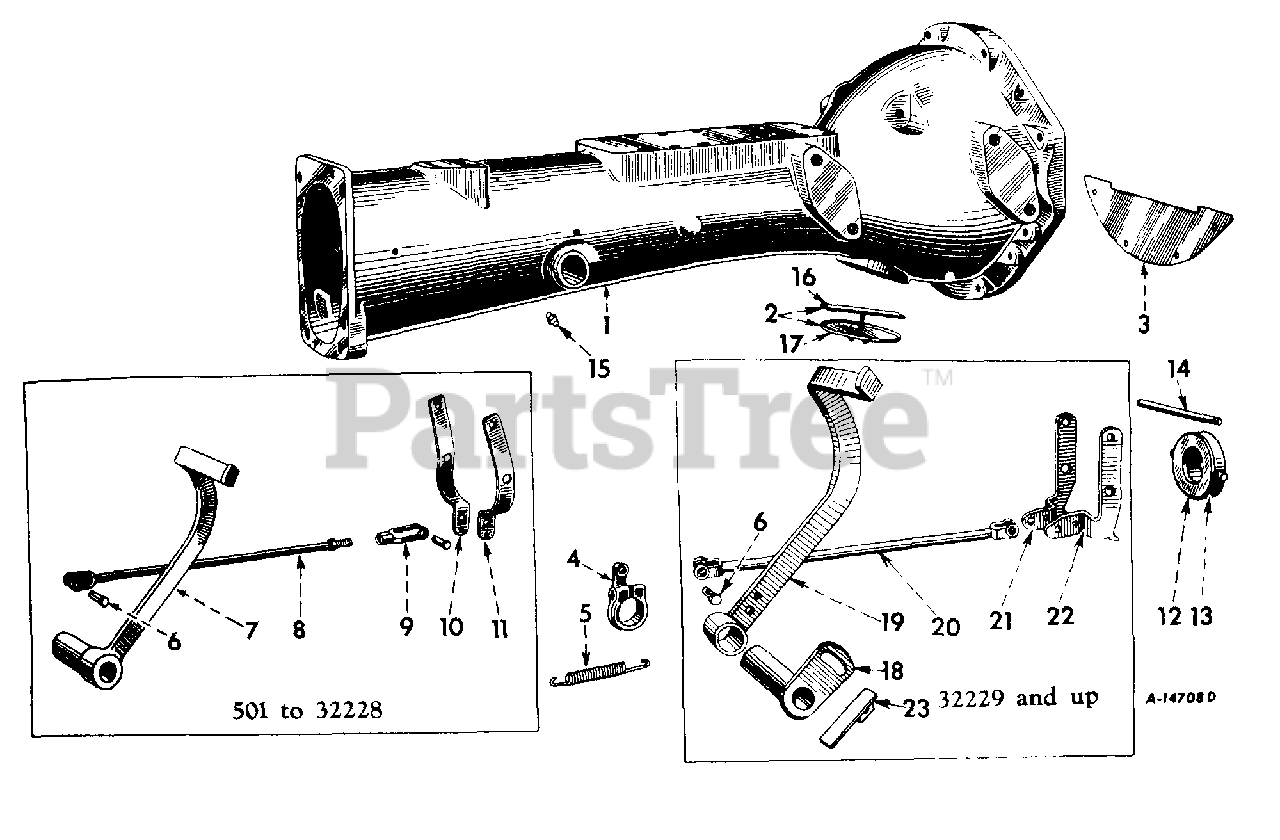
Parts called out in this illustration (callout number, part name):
1	HOUSING, CLUTCH
2	COVER
3	COVER, CLUTCH HOUSING
4	LEVER, CLUTCH PEDAL
5	SPRING CLUTCH PEDAL RETURN
6	PIN, 3/8 X 1-3/32
7	PEDAL ASSY, CLUTCH
8	ROD, CLUTCH OPERATING
9	YOKE, ADJUSTABLE CLUTCH OPERATING ROD
10	YOKE, CLUTCH RELEASE LEFT SIDE
11	YOKE, CLUTCH RELEASE RIGHT SIDE
12	FITTING, 1/4-28 NS TAPER STR LUB
13	BEARING AND RETAINER, CLUTCH RELEASE
14	PIN, CLUTCH RELEASE YOKE PIVOT
15	FITTING, 3/16 STR DRIVE TYPE LUB
16	BAR ASSY, CLUTCH HOUSING HAND HOLE COVER
17	COVER, CLUTCH HOUSING HAND HOLE
18	PLATE ASSY, CLUTCH ADJUSTING
19	PEDAL ASSY, CLUTCH
20	ROD ASSY, CLUTCH OPERATING
21	YOKE, CLUTCH RELEASE LEFT SIDE
22	YOKE, CLUTCH RELEASE RIGHT SIDE
23	SPRING, ACTUATING
